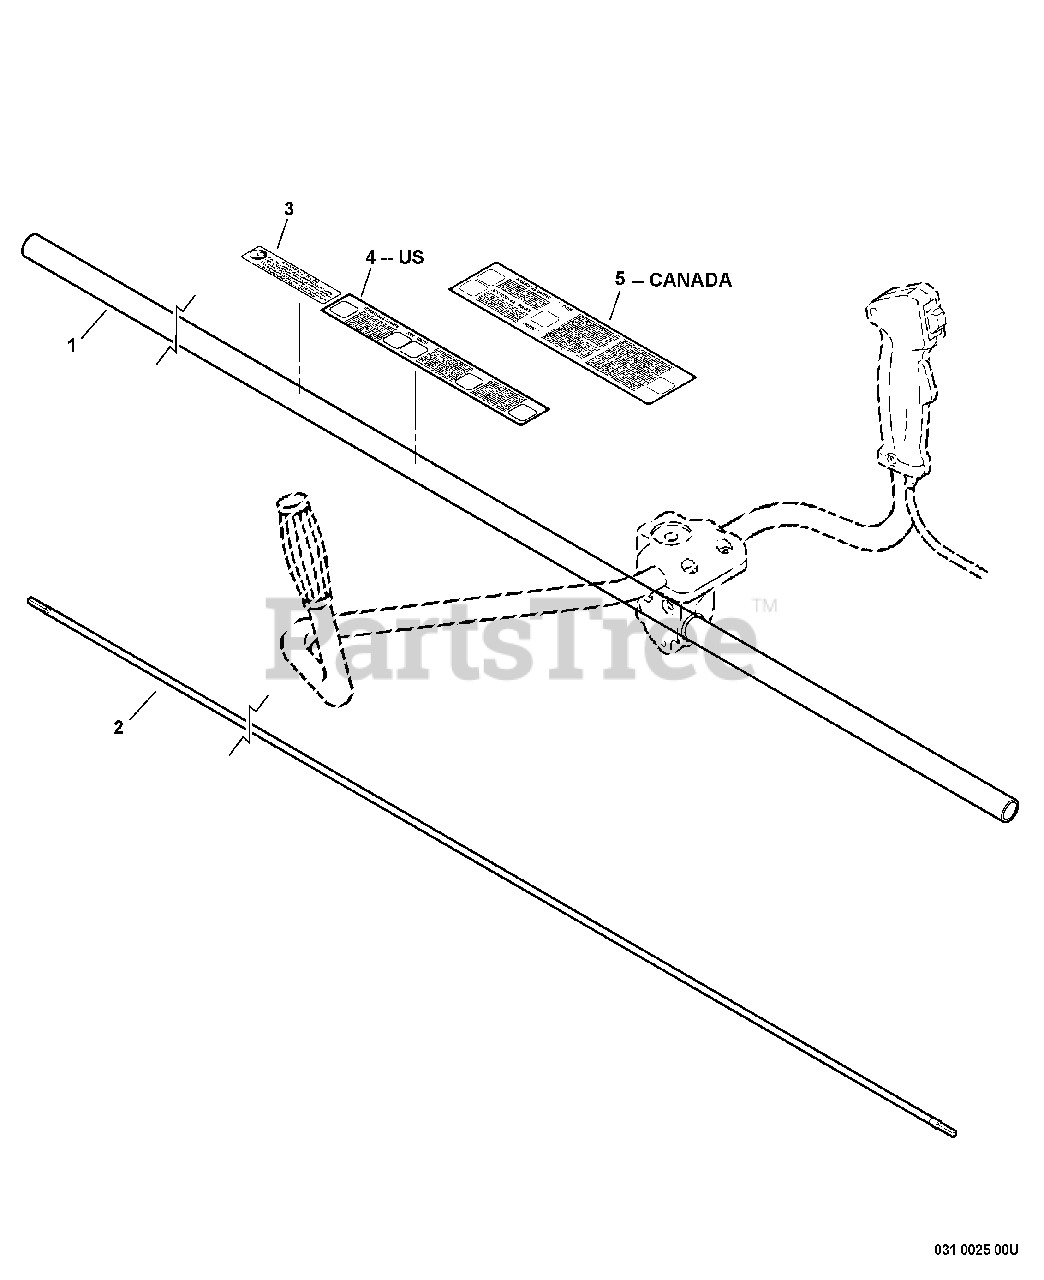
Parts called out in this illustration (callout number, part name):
1	PIPE, MAIN
2	DRIVESHAFT - SOLID
3	LABEL - CAUTION -- SPANISH
4	LABEL - CAUTION
5	LABEL - CAUTION
